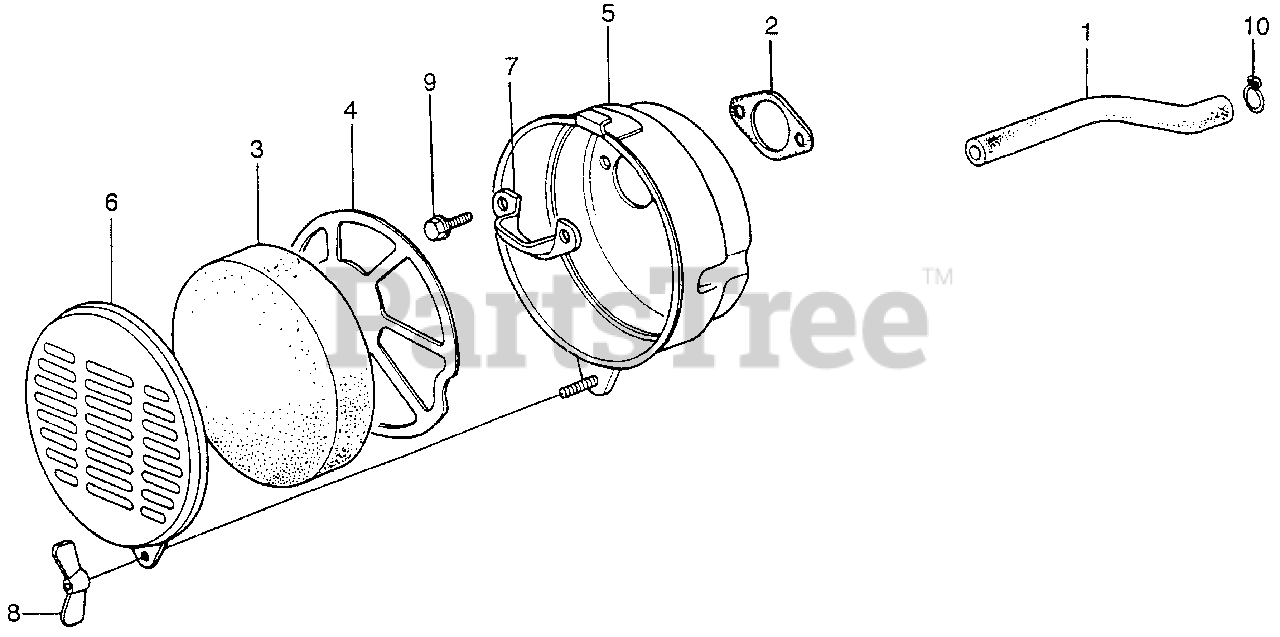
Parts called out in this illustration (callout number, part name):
1	TUBE, BREATHER
2	GASKET, AIR CLEANER (NOT AVAILABLE)
3	ELEMENT, AIR CLEANER
4	GRID, CLEANER (NOT AVAILABLE)
5	HOUSING, AIR CLEANER *R8* (BRIGHT RED) (NOT AVAILABLE)
6	COVER, AIR CLEANER *R8* (BRIGHT RED) (NOT AVAILABLE)
7	PLATE, BAFFLE
8	WINGNUT, TOOL BOX SETTING
9	BOLT, HEX. (6X12)
9	BOLT, FLANGE (6X12)
10	CLIP, TUBE (B12.5)
